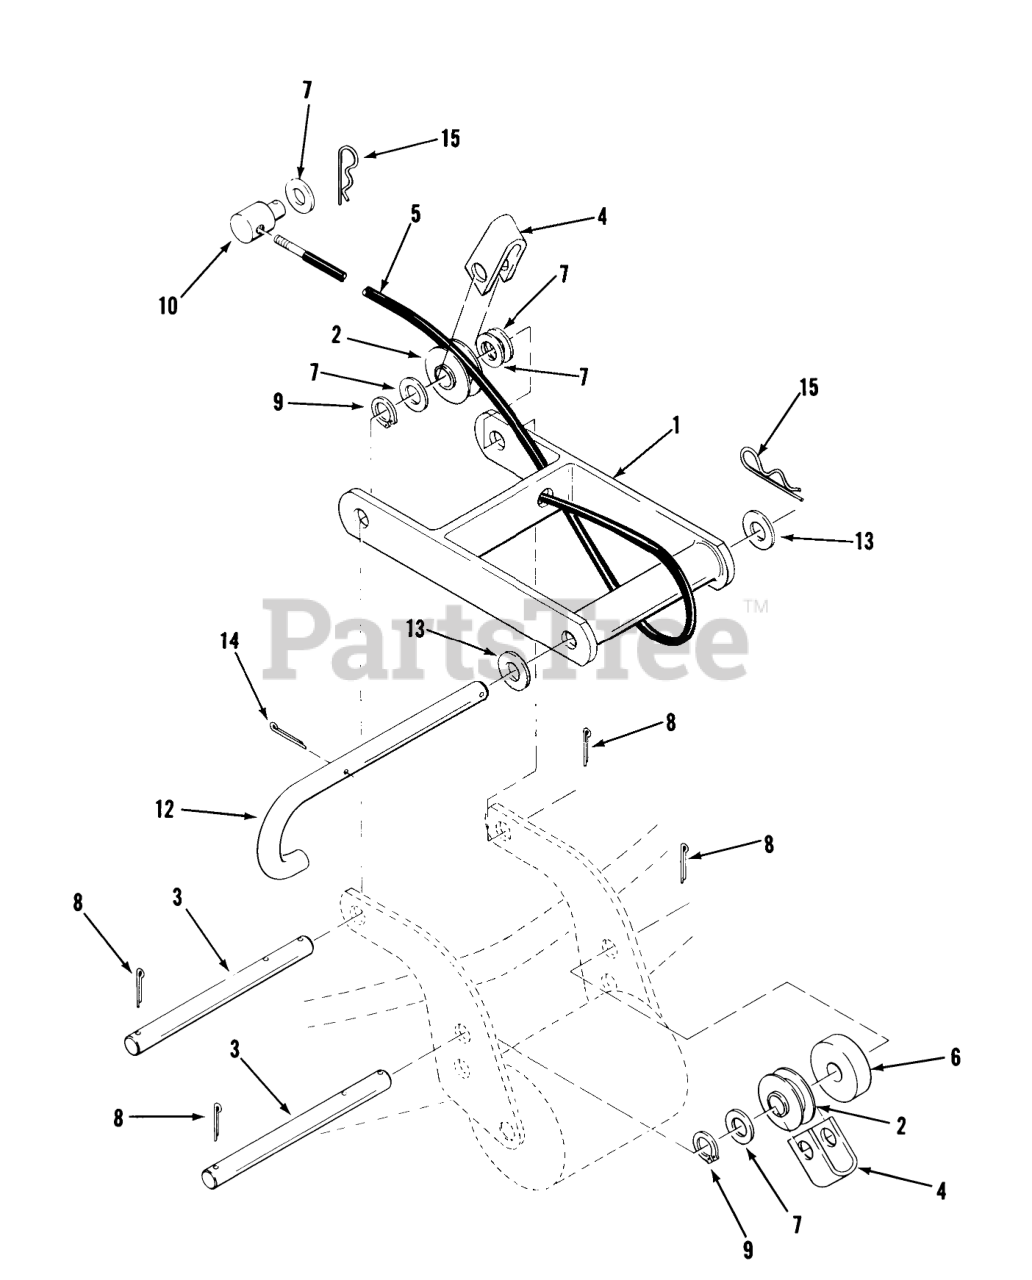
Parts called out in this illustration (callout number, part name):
1	ASSY-FRNT HSG MOUNT
1	Front Mount
2	ROLLER-CABLE
3	Rod
4	STRAP-CABLE
5	ASSY-CABLE
5	ASSY CABLE
6	SPACER
7	Washer
8	Pop Rivet
9	GRIP RING
10	TRUNNION-CLUTCH ROD
12	"J" Pin
13	Washer
15	Hairpin Cotter
